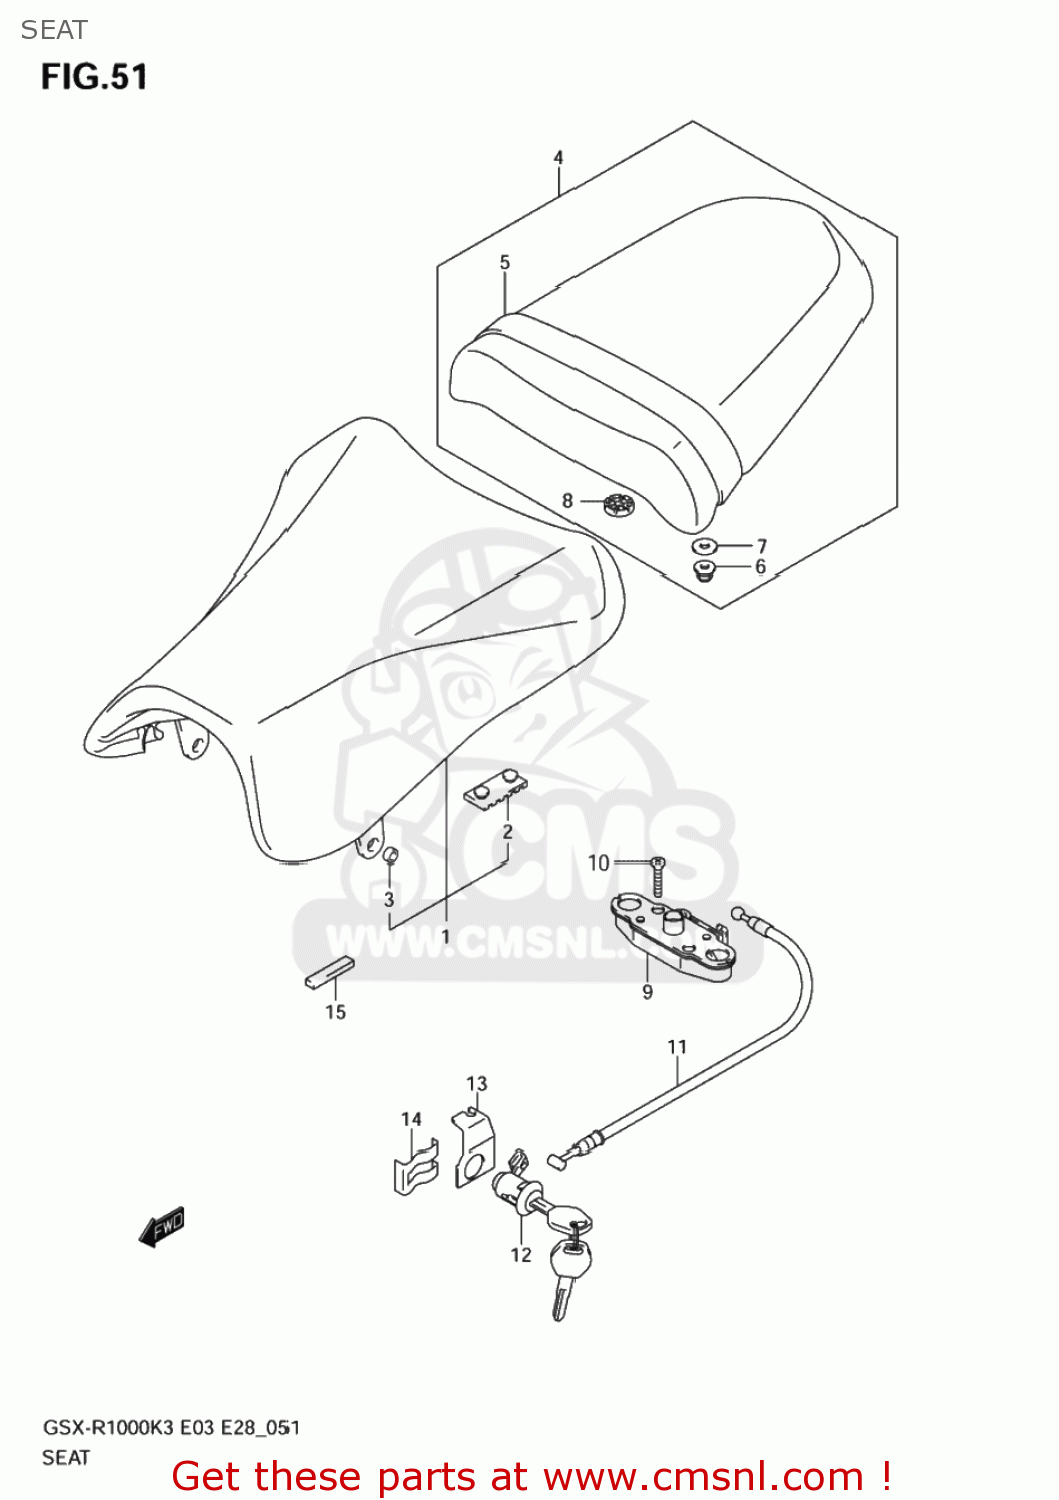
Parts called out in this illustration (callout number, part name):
1	SEAT ASSY
2	CUSHION,SEAT(40X20X6)
3	SPACER,SEAT(6.5X10.5X6)
4	SEAT ASSY,PILLION
5	BAND,SEAT
6	NUT
7	WASHER(6.5X20X1.6)
8	CUSHION
9	BRACKET,SEAT SUPPORT,RIGHT
10	SCREW
11	CABLE,SEAT LOC
12	LOCK SET,SEAT
13	GUIDE,SEAT LOCK CABLE
14	PLATE,SEAT LOCK ASSY
15	CUSHION
